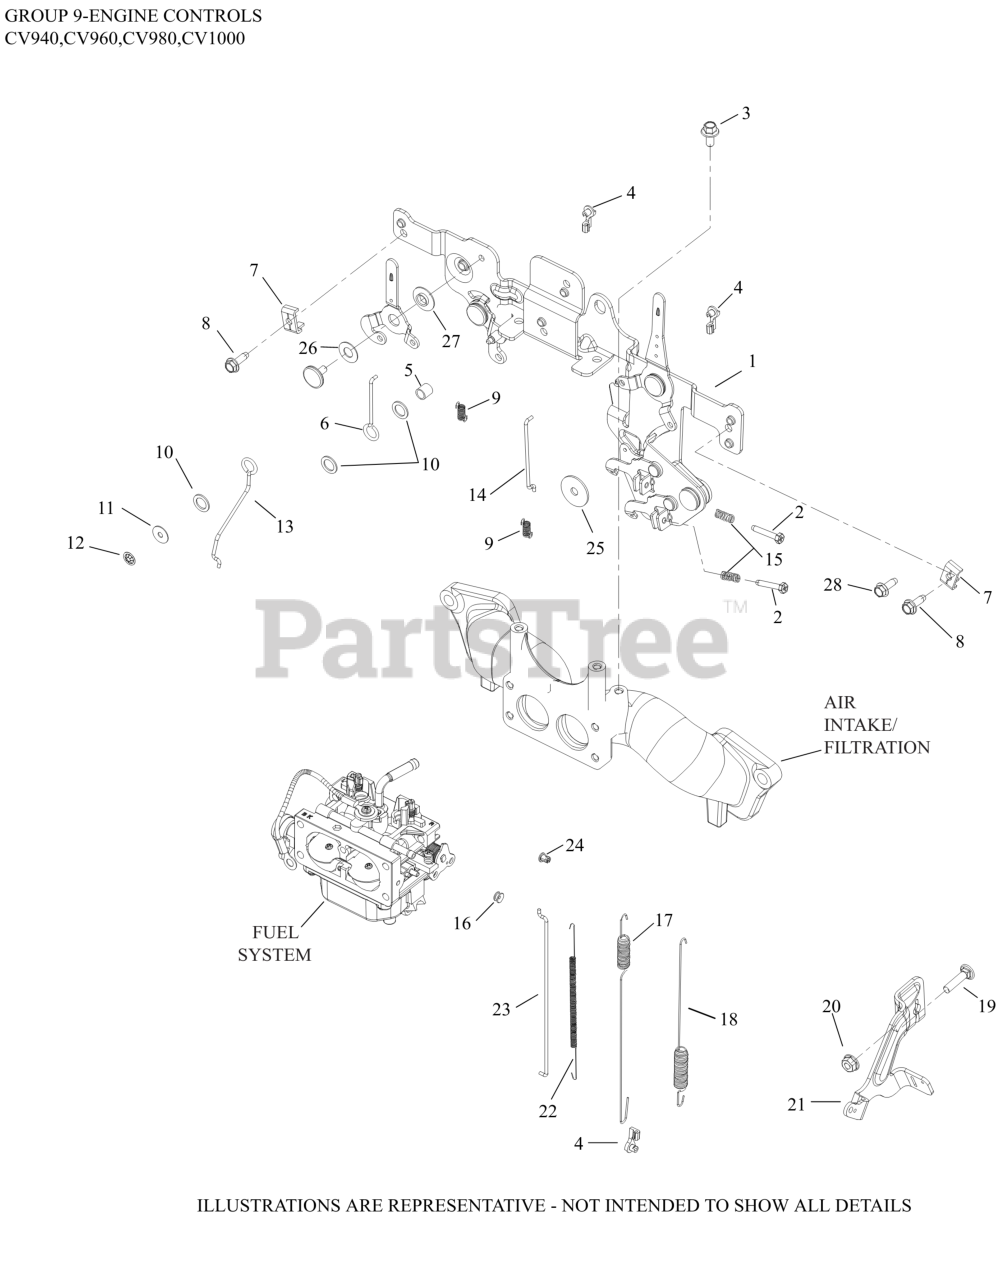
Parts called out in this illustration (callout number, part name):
1	CONTROL ASSEMBLY, SPEED VERTICAL
2	SCREW, PHL THD FRM M4X0.7X25
3	SCREW, FLG M6X1.0X12
4	BUSHING, THROTTLE LINKAGE
6	LINKAGE, CONTROL
7	CLAMP, CABLE-(#2523753S)
9	SPRING, RETURN
10	WASHER, NYLON
11	WASHER, STEEL
12	RETAINER, PALNUT
13	LINKAGE, CHOKE
14	LINKAGE, THROTTLE LEVER
15	SPRING, SPEED CONTROL (SHORT)
17	SPRING, GOVERNOR (3751-3900)
18	SPRING,GOV (VERT IDLE 1626-1800)
19	BOLT, RD HD SQ NECK M6X1.0X25
20	NUT, FLG M6X1.0
21	KIT, GOVERNOR LEVER
22	SPRING, LINKAGE
23	LINKAGE, THROTTLE
24	BUSHING, LINKAGE RETAINING
26	WASHER, FLAT 9 MM
27	WASHER, NYLON SHOULDER
28	SCREW, THREAD FORMING
